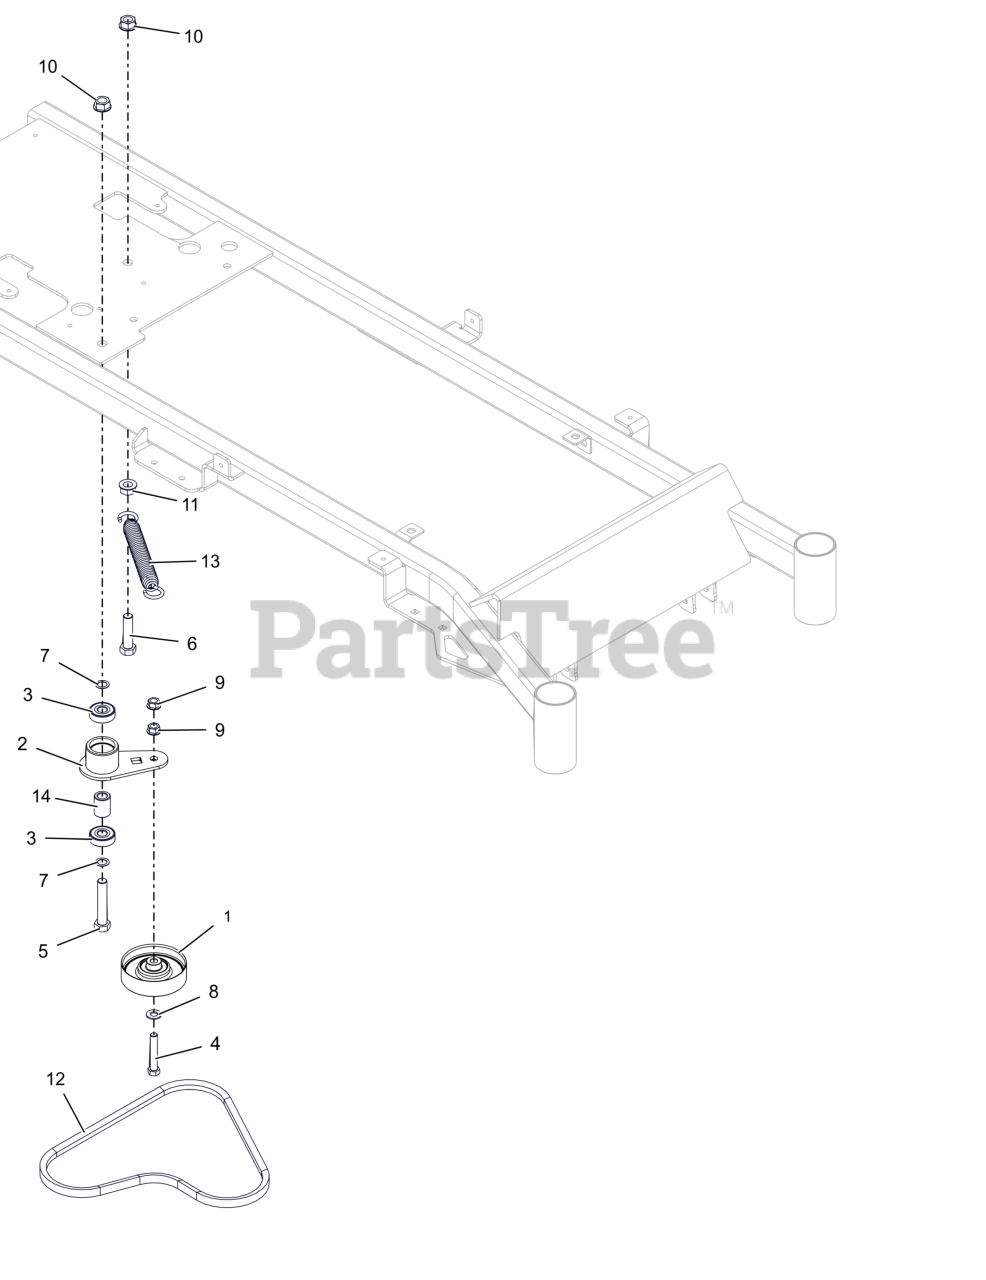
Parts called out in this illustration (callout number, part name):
1	IDLER- FLAT 3.5" NO FLANGES
2	WLDMT, 32" IDLER ARM
3	BRG-BALL .500X1.38X.437
4	BLT,HEX .38-16X2.25 G5 ZCC
5	BLT,HEX .50-13X2.75 G5 ZCC
6	BLT, HEX .50-13X2.00 G5 ZCC
7	WASHER, .500X.750X.020 THRUST
8	WSHR,FLT .406X.812X.065 ZCC
9	NUT-LK-CTR-FLG .375-16 GF ZCC
10	NUT-LK-CTR-FLG .500-13 GG ZCC
11	NUT, SPNLK-FLG .50-13 G5 ZCC
12	BELT, HA SECTION
13	SPRING- EXTENSION
14	SPACER .510 X .867 X 1.1485
